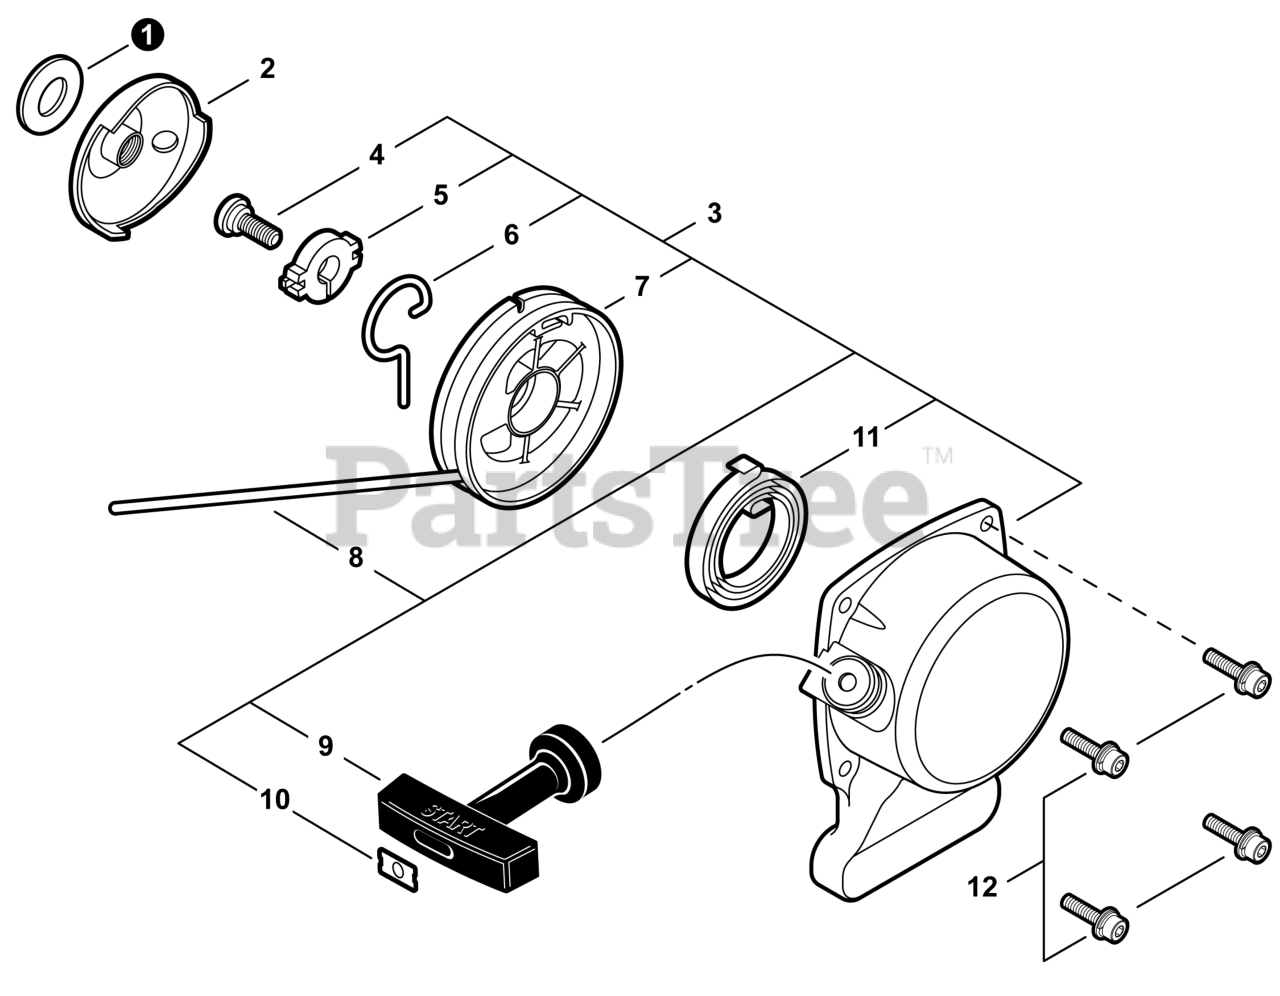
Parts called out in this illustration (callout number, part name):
1	WASHER 8
2	PULLEY, STARTER
3	STARTER ASSY, RECOIL
4	SCREW 5
5	WASHER 5
6	ARM, SWING
7	REEL, ROPE
8	ROPE, STARTER
9	GRIP, STARTER
10	RETAINER, ROPE
11	SPRING, RECOIL
12	BOLT M4×16
